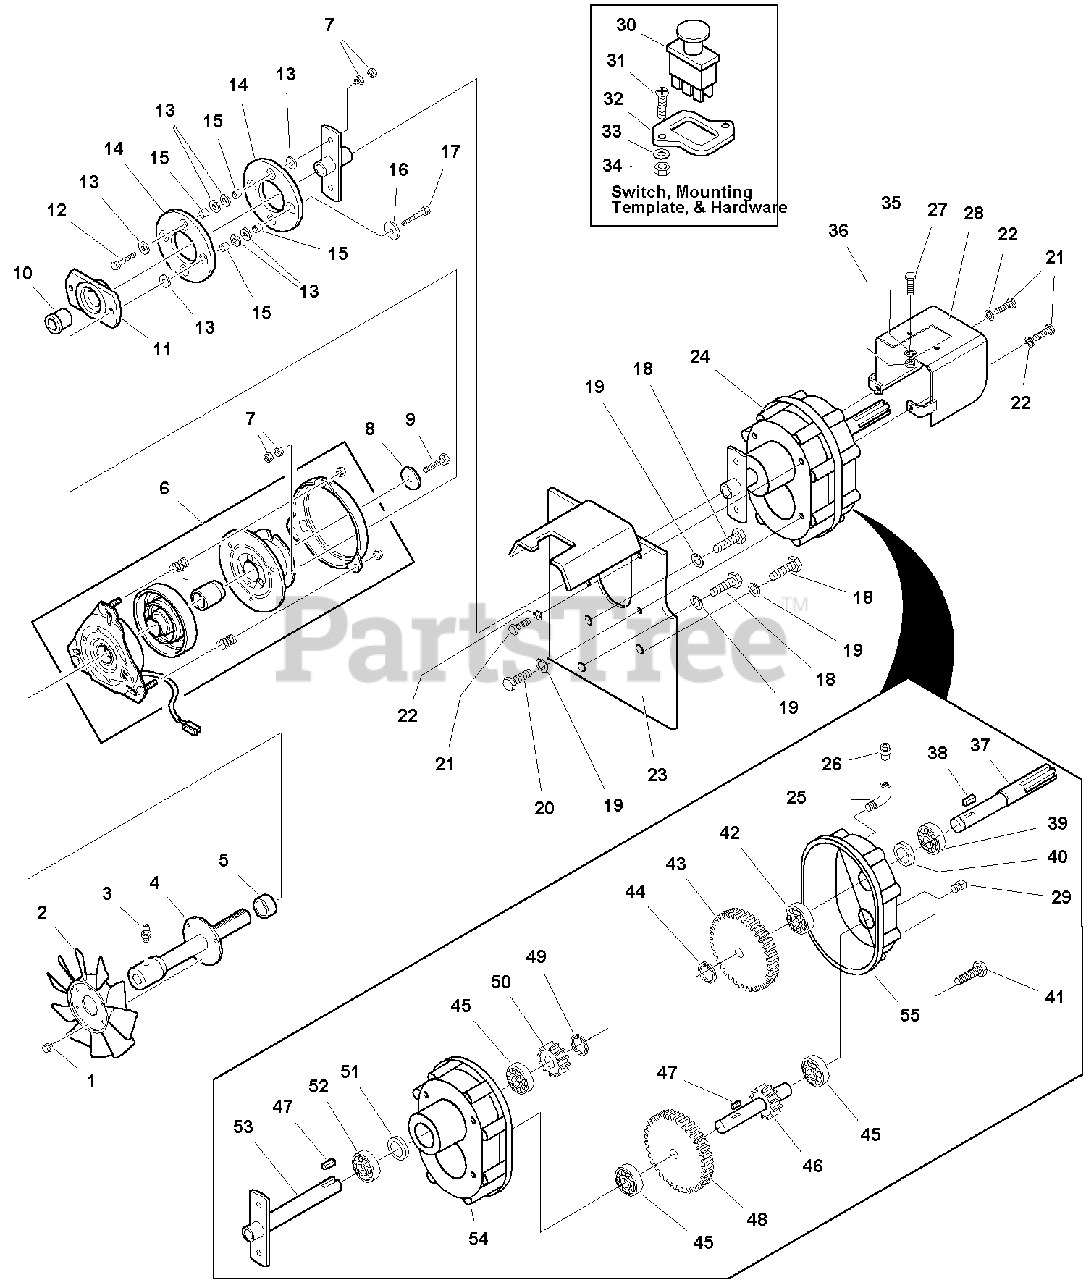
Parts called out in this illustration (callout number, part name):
1	SCREW, Taptite, 10-24 x 1/2
2	FAN, 10 Blade
3	FITTING, Grease
4	SHAFT ASSEMBLY (Incl. Ref. No. 5)
6	CLUTCH, Eletric, Sun Star Rear P.T.O.
7	LOCKNUT, 5/16-18
9	CAPSCREW, Hex Head 5/16-18 x 2 G5
11	HUB ASSEMBLY
12	CAPSCREW, Hex Head, 5/16-18 x 1-1/4
13	WASHER, 5/1 6
17	CAPSCREW, Hex Head 5/16-18 x 2 G5
18	CAPSCREW, Hex Head, 1/2-13 x 2
19	LOCKWASHER, 1/2
20	CAPSCREW, Hex Head, 1/2-13 x 1
21	CAPSCREW, Hex Head, 3/8-16 x 1
22	LOCKWASHER, 3/8
23	MOUNTING PLATE
26	VENT ASSEMBLY
27	CAPSCREW, Hex Head, 5/16-18 x 1
28	SHIELD ASSEMBLY
30	SWITCH, PTO
31	SCREW, Truss Head, 10-32 x 1/2
32	MOUNTING TEMPLATE
34	NUT, Hex, 10-32
35	LOCKWASHER, 5/16
36	NUT, Hex, 5/16-18
41	CAPSCREW, Hex Head, Metric
44	RETAINING RING
46	SHAFT & GEAR ASSEMBLY
49	RETAINING RING
53	SHAFT, Input
54	GEAR CASE HALF, Not Available
55	GEAR CASE HALF, Not Available
